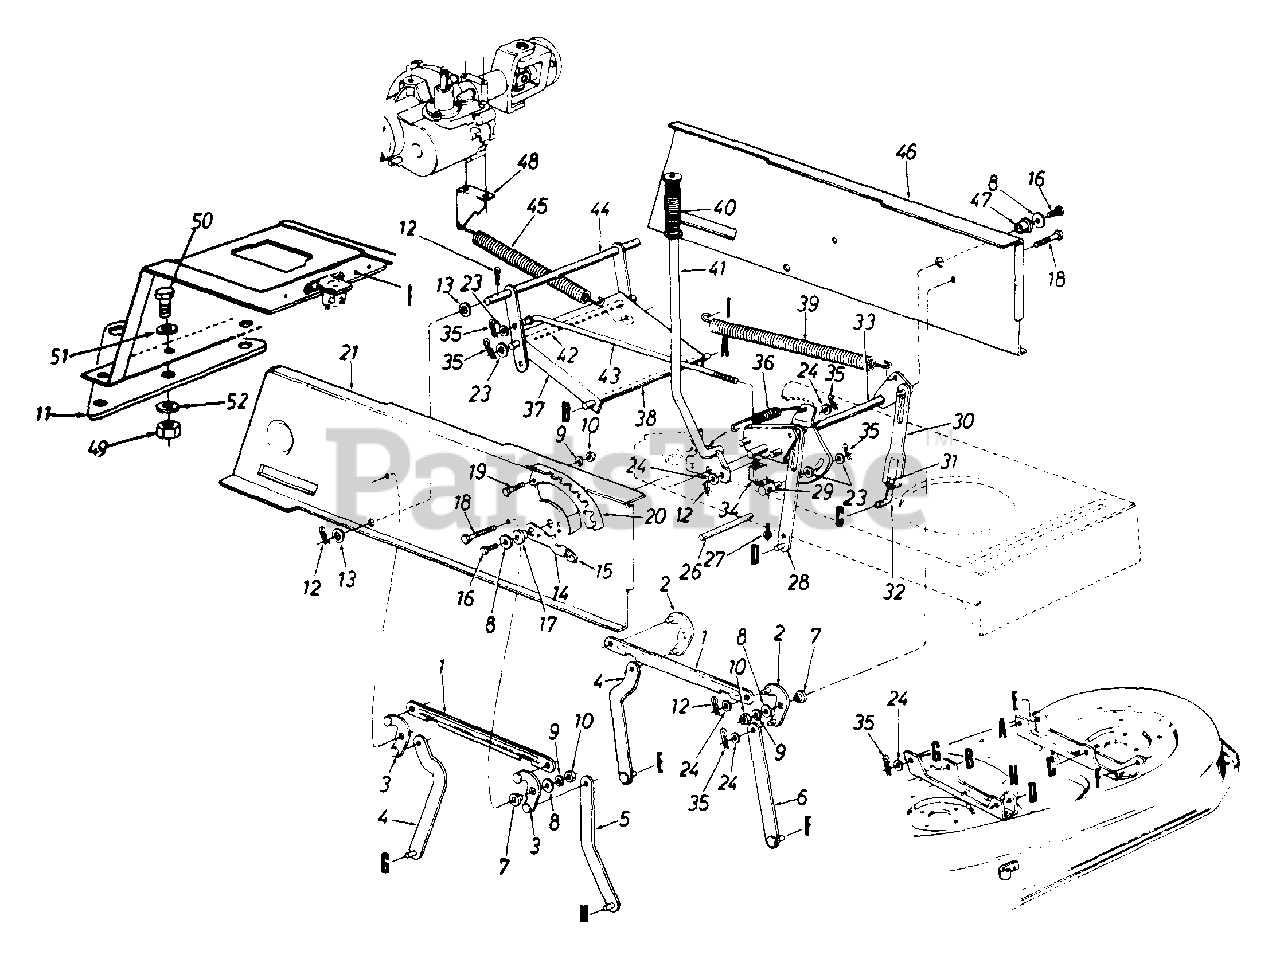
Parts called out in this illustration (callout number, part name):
1	Connecting Rod
2	Pivot Link Ass'y.- L.H.
3	Pivot Link Ass'y.- R.H.
7	Shld. Spacer .318" I.D.
8	Fl-Wash. .344" l.D. x 1.125"
9	L-Wash. 5/16" I.D.
10	Hex Nut 5/16-18 Thd.
11	Hitch Plate Extension
12	Cotter Pin 1/8" Dia.
13	Fl-Wash. .635" I.D. x 1.0" O.D.
14	Deck Lift - Down Stop
15	Knob
16	Hex Wash. TT-Tap Scr. 5/16-18 x .75" Lg.
17	Flange Brg. .63" I.D.
18	Hex Wash. TT-Tap Scr. 5/16-18 x .875" Lg.
19	Hex Bolt 5/16-18 x .75" Lg.
20	Index Brkt.
21	Upper Frame - R.H.
23	Fl-Wash. .385" I.D. x .87" O.D.
24	Fl-Wash. .531" I.D. x .93" O.D.
26	Running Board Rod
27	Truss Mach. Scr. #10 x .5" Lg.
31	Hex Nut 1/2-20 Thd. (Gr. 5)
32	Lift Link Adjuster
33	Lift Shaft Ass'y.
34	Safety Switch (Deck)
35	Inter. Cotter Pin 3/8" Dia.
36	Extension Spring
37	Stabilizer Bracket
38	Shaft 1/2" Dia. x 10.28" Lg.
39	Extension Spring
40	Grip (Lift Handle)
41	Deck Lift Handle Ass'y.
42	Shaft 3/8" Dia. x 9.34" Lg.
43	Disengagement Rod
44	Stabilizer Shaft Ass'y.
45	Extension Spring 7.58" Lg.
46	Upper Frame - L.H.
47	Flange Brg. .632" I.D.
48	Spring Retainer Brkt.
49	Hex Nut 7/16-14 Thd. (Gr. 5)
50	Hex Bolt 7/16-14 x 1" Lg.
51	Bell-Wash. .46" I.D.
52	Fl-Wash. .469" I.D. x 1.13" O.D.
